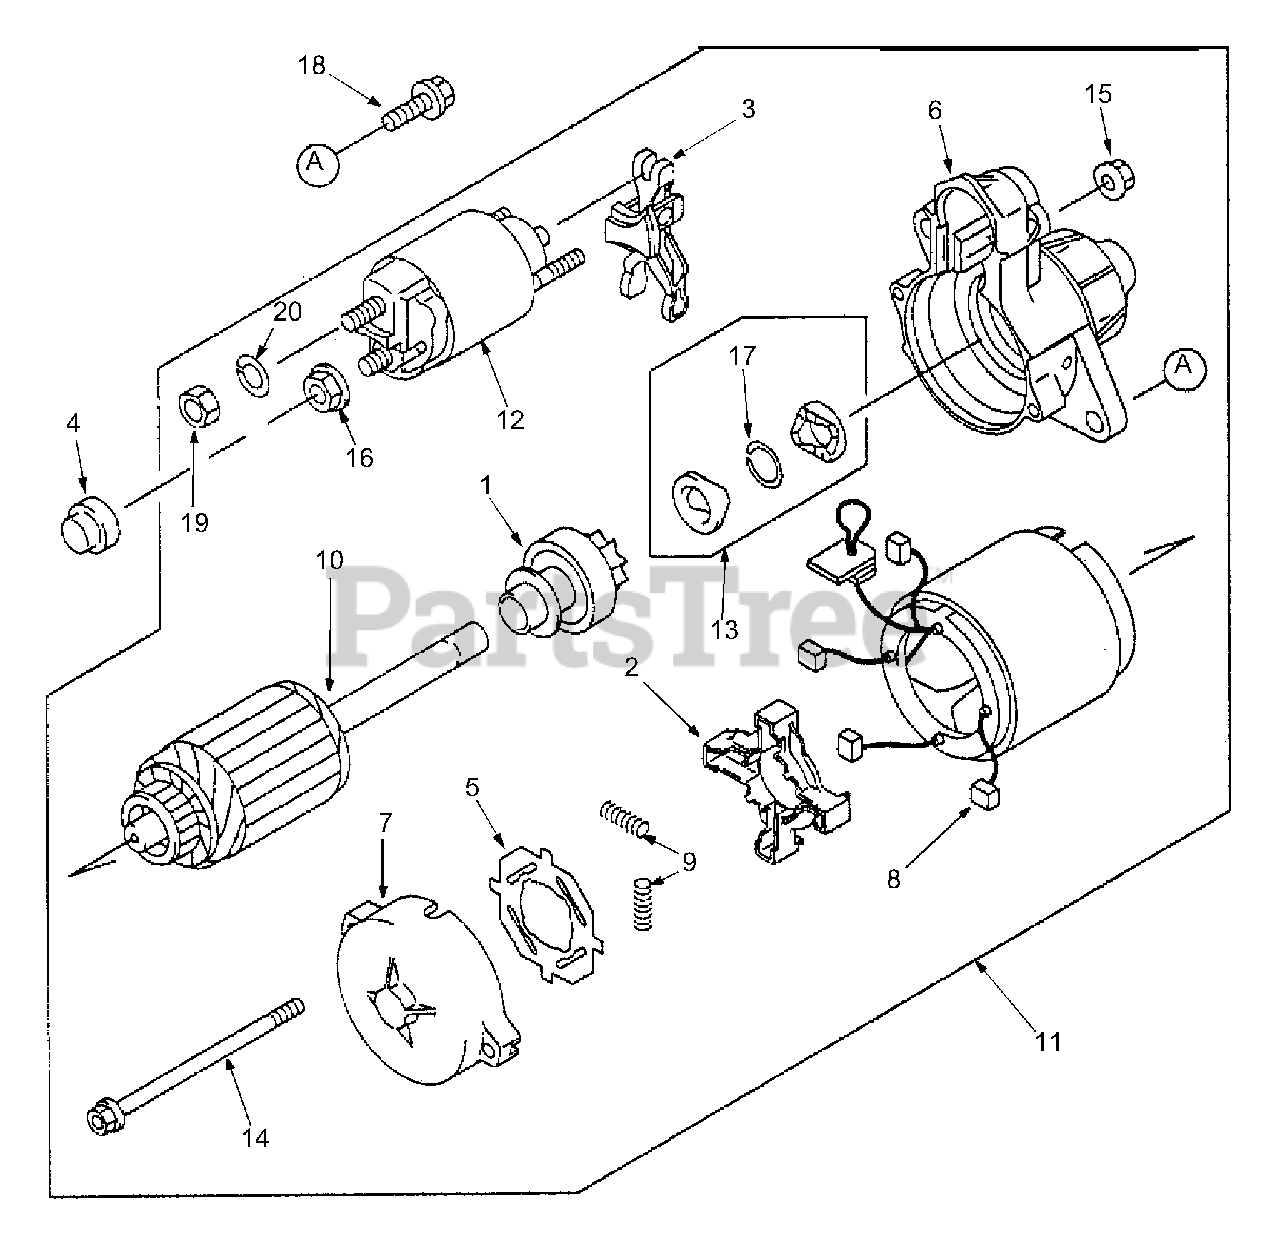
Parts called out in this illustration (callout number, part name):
2	Holder, Brush
9	Spring, Brush
11	Starter, Complete
12	Switch, Solenoid
13	Stopper
18	Bolt, Flanged
19	Nut, Hex 8 MM
20	Washer, Spring, 8MM
